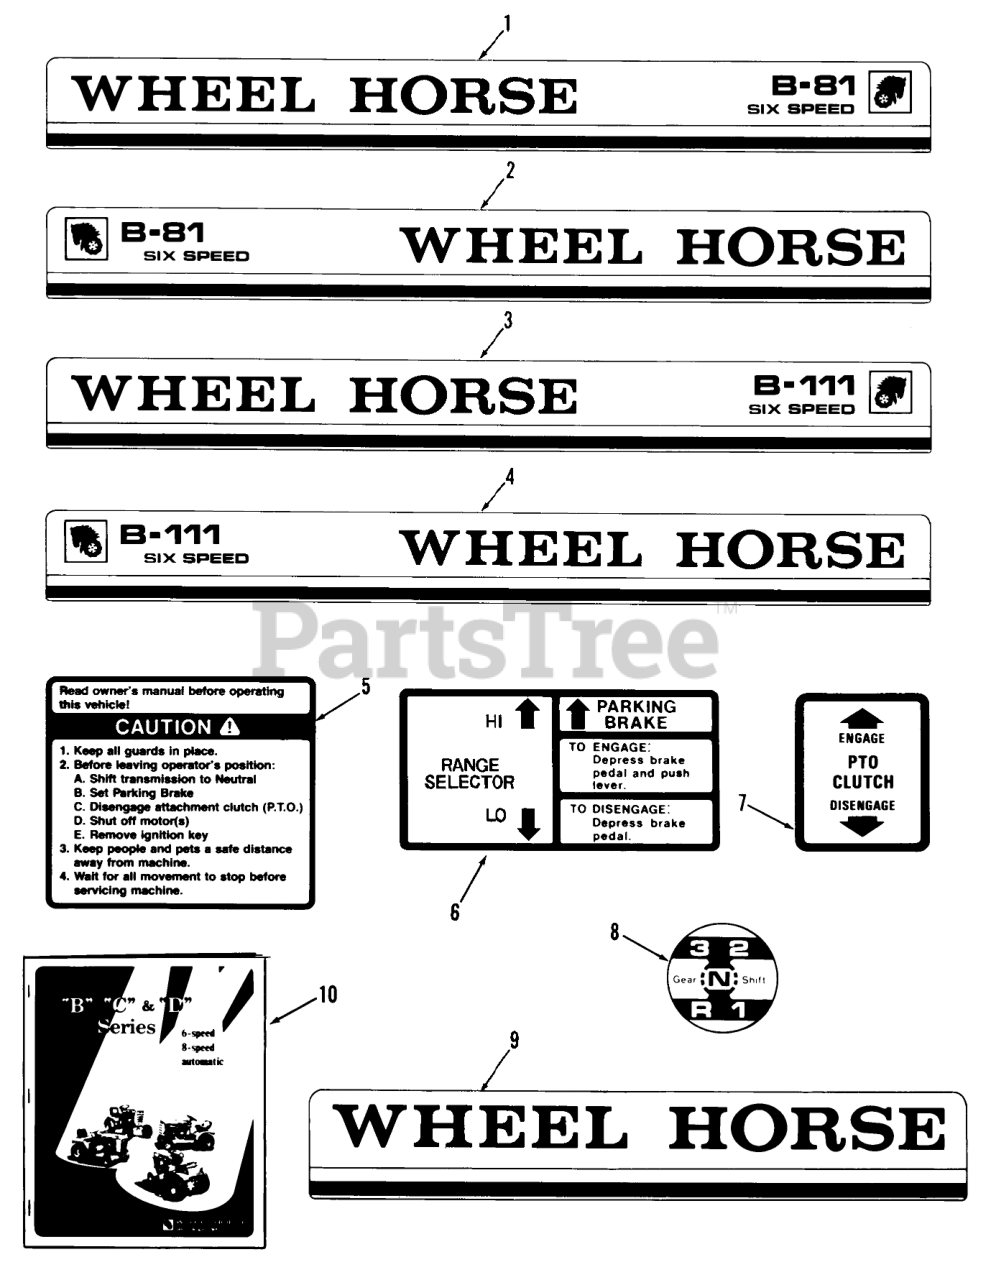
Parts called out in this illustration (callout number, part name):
1	Decal-Hood B-81 RH
2	Decal-Hood B-81 LH
3	DECAL HOOD RH
4	DECAL HOOD LH
5	DECAL-CAUTION
6	Decal-Parking Brake & HI-Lo Control
7	DECAL-PTO CLUTCH
8	Coil Spring
9	Decal-Rear
10	Owner-s Manual
